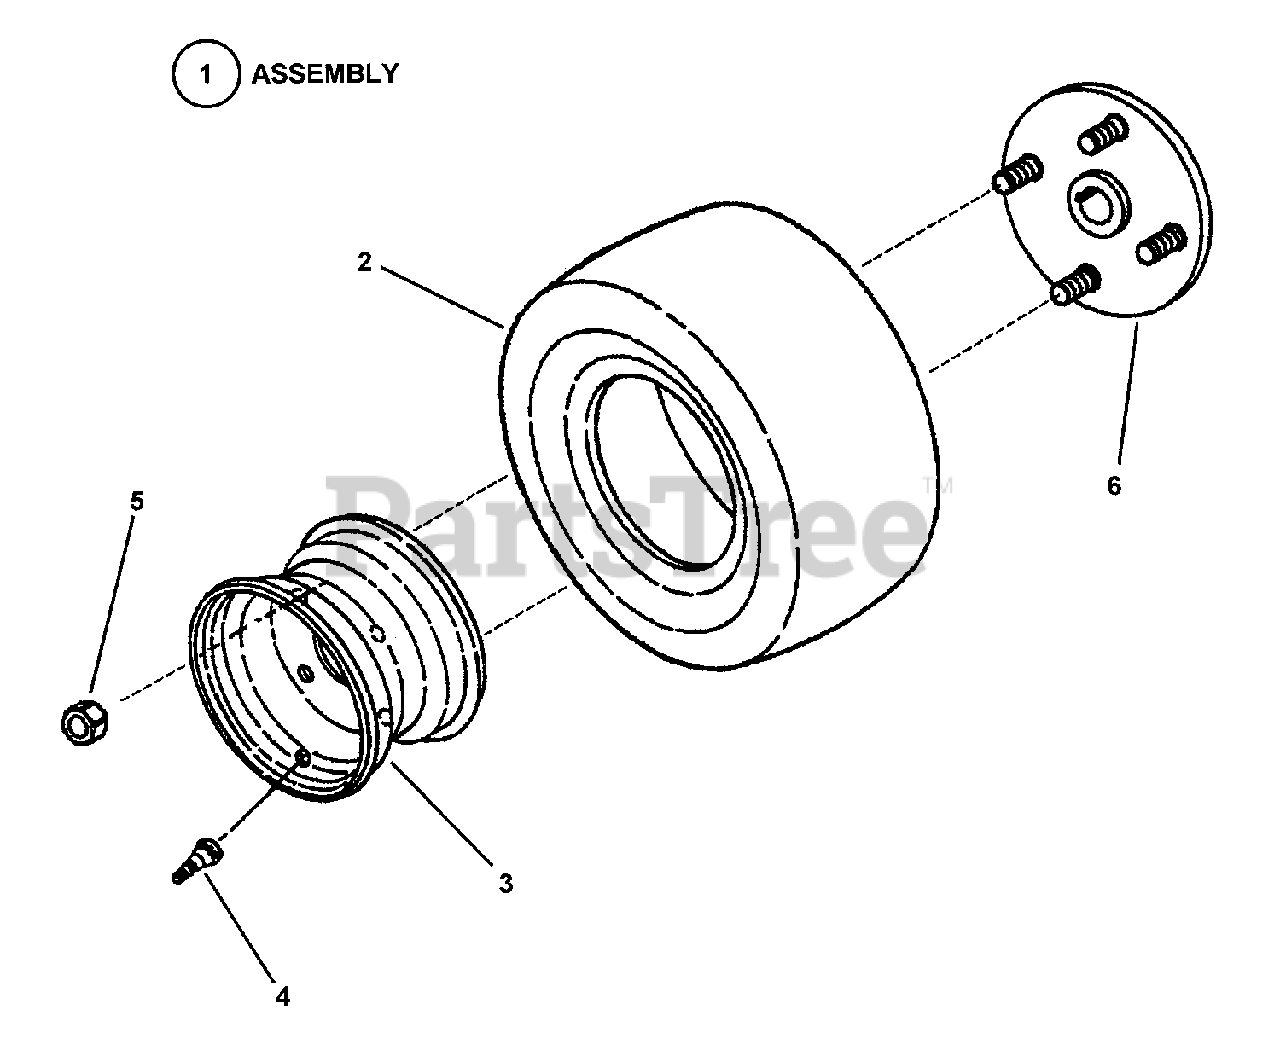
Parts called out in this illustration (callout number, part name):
1	ASSEMBLY, Rear Tire & Rim
1	ASSEMBLY, Rear Tire & Rim, Turf Saver, Gray
2	TIRE, 16 x 6.50-8, 4 Ply (Carlisle "Turf Chief")
3	RIM (White)
3	RIM (Gray)
4	AIR VALVE, Snap-In
5	LUG-NUT, 1/2-20 Tapered Seat
6	WHEEL HUB, w/4 threaded studs
